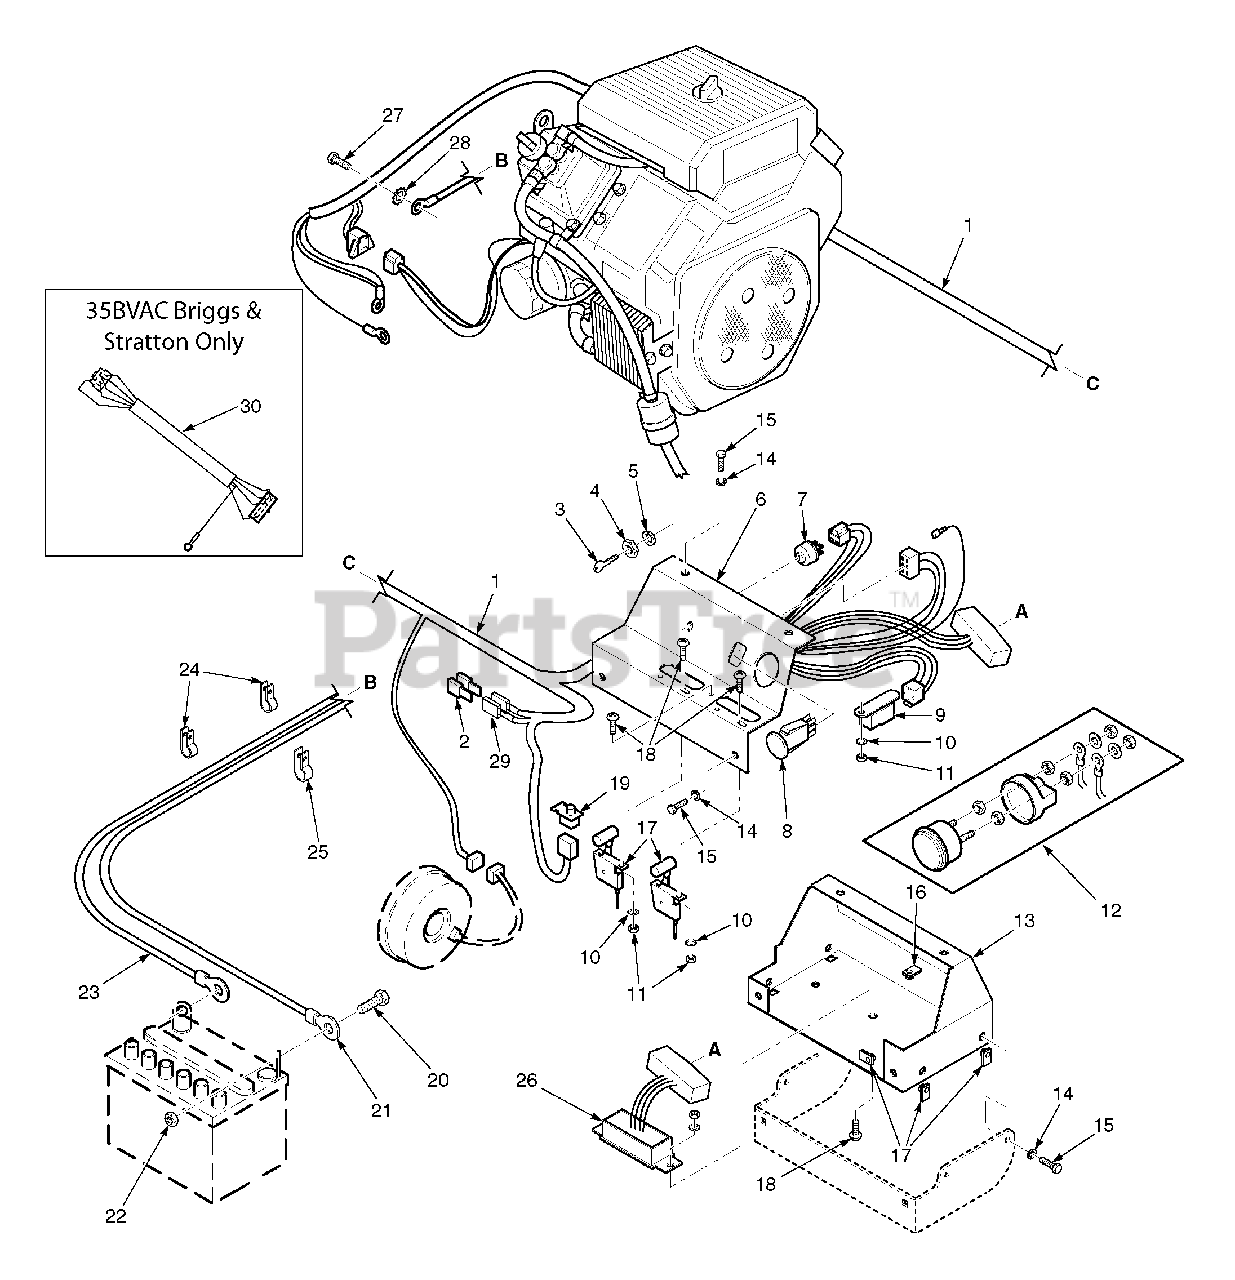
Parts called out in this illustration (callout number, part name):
1	Wire Harness, STT Air Cooled
2	Fuse, 20 AMP
3	Key & Ring Assembly
4	Nut, Hex 5/8-32
5	Lockwasher, 5/8" Internal
6	Instrument Panel, Top w/Decals
7	Key Switch
8	Switch, PTO
9	Relay
10	Lockwasher, #10 External Tooth
11	Nut, Hex #10-32
12	Ammeter
13	Base, Instrument Panel
14	Lockwasher, 1/4"
15	Bolt, Hex Head 1/4-20 x 3/4"
16	U-Nut, 1/4-20
17	Throttle And Choke Controls
18	Screw, Phillips Washer Head #10-32 x 1/2"
19	Switch, Interlock-Seat
20	Bolt, Hex Head 1/4-20 x 1/2"
21	Cable, Battery - Red
22	Nut, Hex 1/4-20
23	Cable, Battery - Black
24	Clamp, Cable 1/2" ID.
25	Clamp, Cable 3/4" ID.
26	Electronic Module
27	Bolt, Hex Head M8-1.25 x 20
28	Lockwasher, 5/16" External Tooth
29	Fuse Holder w/Fuse and Connector
30	Wire Harness Adapter
